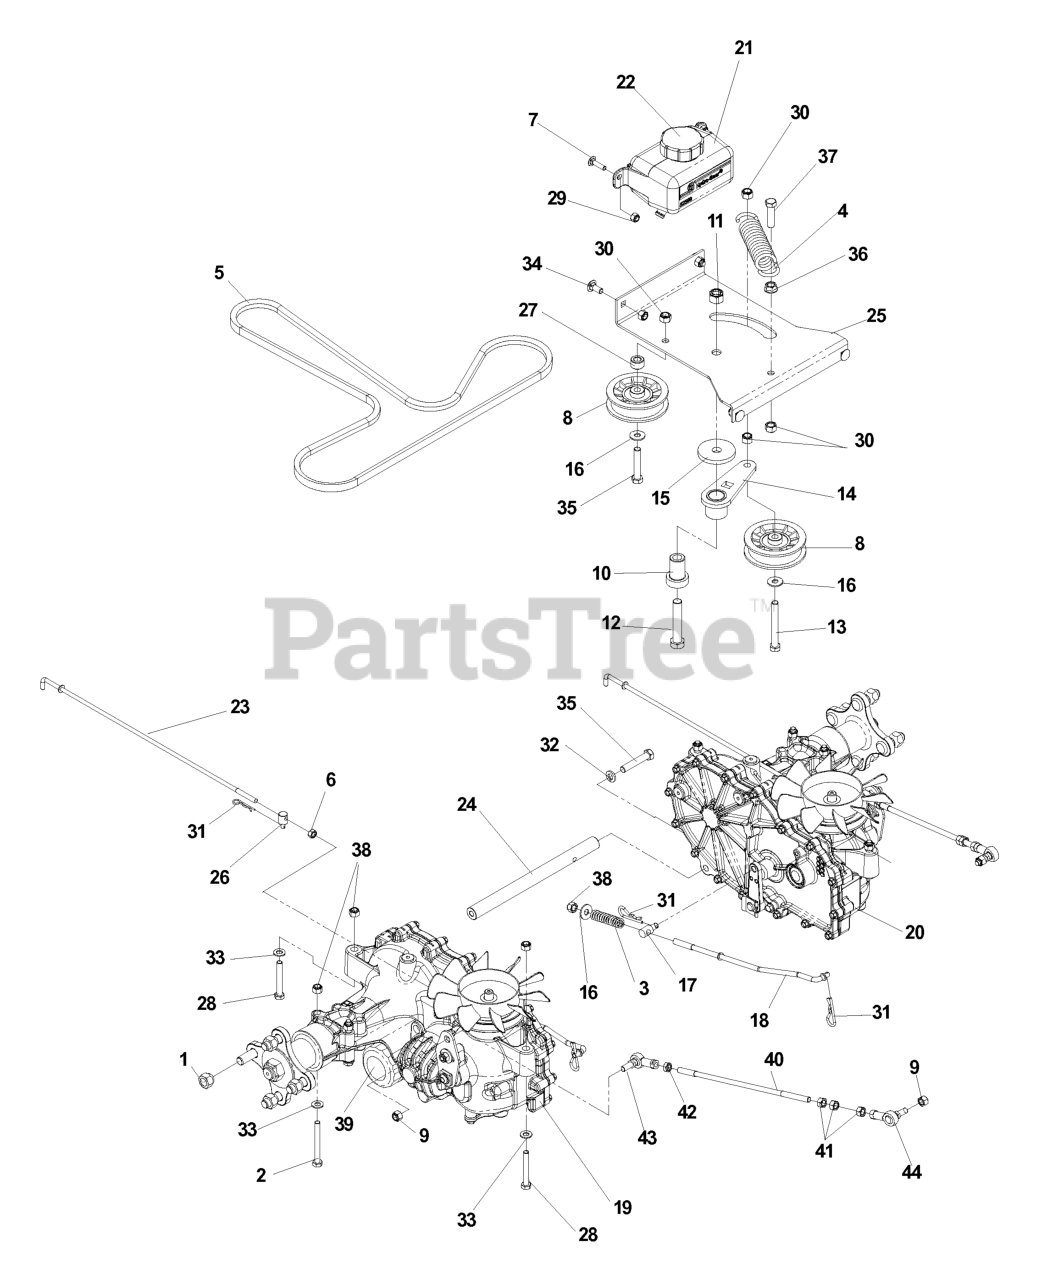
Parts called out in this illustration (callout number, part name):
1	LUG NUT 1/2F
2	HCS 5/16C X 2-3/4
5	PUMP BELT
6	NUT 1/4-28 HEX ZD
7	RHSNB, 1/4-20 X 1, GR5
8	PULLEY, IDLER RAKE & ZTR
9	NUT 5/16F NYLOC
10	IDLER SPINDLE
11	NUT 1/2-13 HEX NYLOC ZD
12	HCS 1/2C X 2 3/4
13	TAPBOLT, 3/8C X 3
14	RP.IDLER ARM WELDMENT
15	HEAVY WASHER
16	WASHER 5/16 FLAT
17	BRAKE SWIVEL
18	BRAKE LINKAGE, LOWER
19	HG_ZT2800 RIGHT SIDE
20	HG_ZT2800 LEFT SIDE
21	HG_EXPANSION TANK W/CAP 71354
22	HG_CAP 52375
23	BYPASS LINKAGE
24	2800 CROSS SUPPORT
25	IDLER PULLEY PLATE
26	SWIVEL, 1/4-28
29	NUT.1/4-20.HEX.NYLOC.ZD
30	NUT 3/8-16 NYLOC
31	HAIRPIN #2
32	SLW 3/8 STD
33	FLAT WASHER 5/16 SAE
34	BOLT 5/16C X 3/4" CARRIAGE
35	HCS 3/8C X 2
36	NUT 3/8C WHIZ
37	HCS 3/8C X 1 1/2
38	NUT 5/16 NYLOC
39	HG_FILTER, ZT4800 52114
40	DRIVE LINKAGE
42	NUT 5/16F LEFTHAND
43	SPHERICAL ROD END, LH
44	SPHERICAL ROD END, RH
